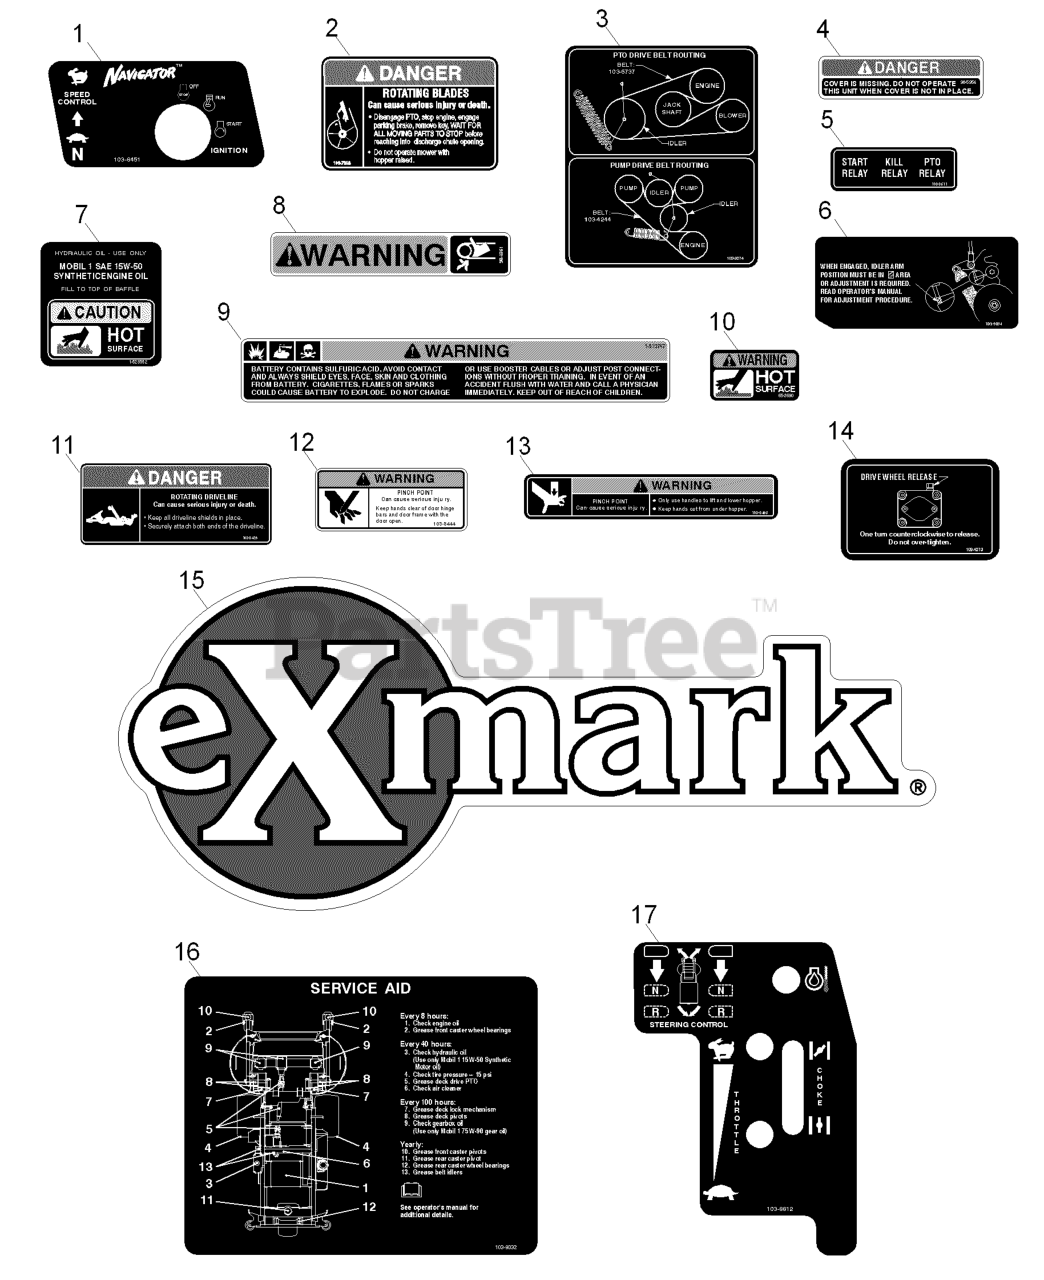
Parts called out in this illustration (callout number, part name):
1	DECAL,IGNITION/SPEED CONT
2	DECAL-DANGER IMPELLER
3	DECAL,BELT ROUTING
4	DECAL-COVER, MISSING
5	DECAL,RELAY
6	DECAL,CLUTCH ADJUSTMENT
8	DECAL-WARNING
9	DECAL-BATTERY
10	DECAL-SURFACE, HOT
11	DECAL-DRIVELINE
12	DECAL-PINCH POINT
13	DECAL,PINCH POINT
14	DECAL,WHEEL MOTOR RELEASE
15	DECAL,EXMARK LOGO
17	DECAL,INSTRUMENT PANEL
